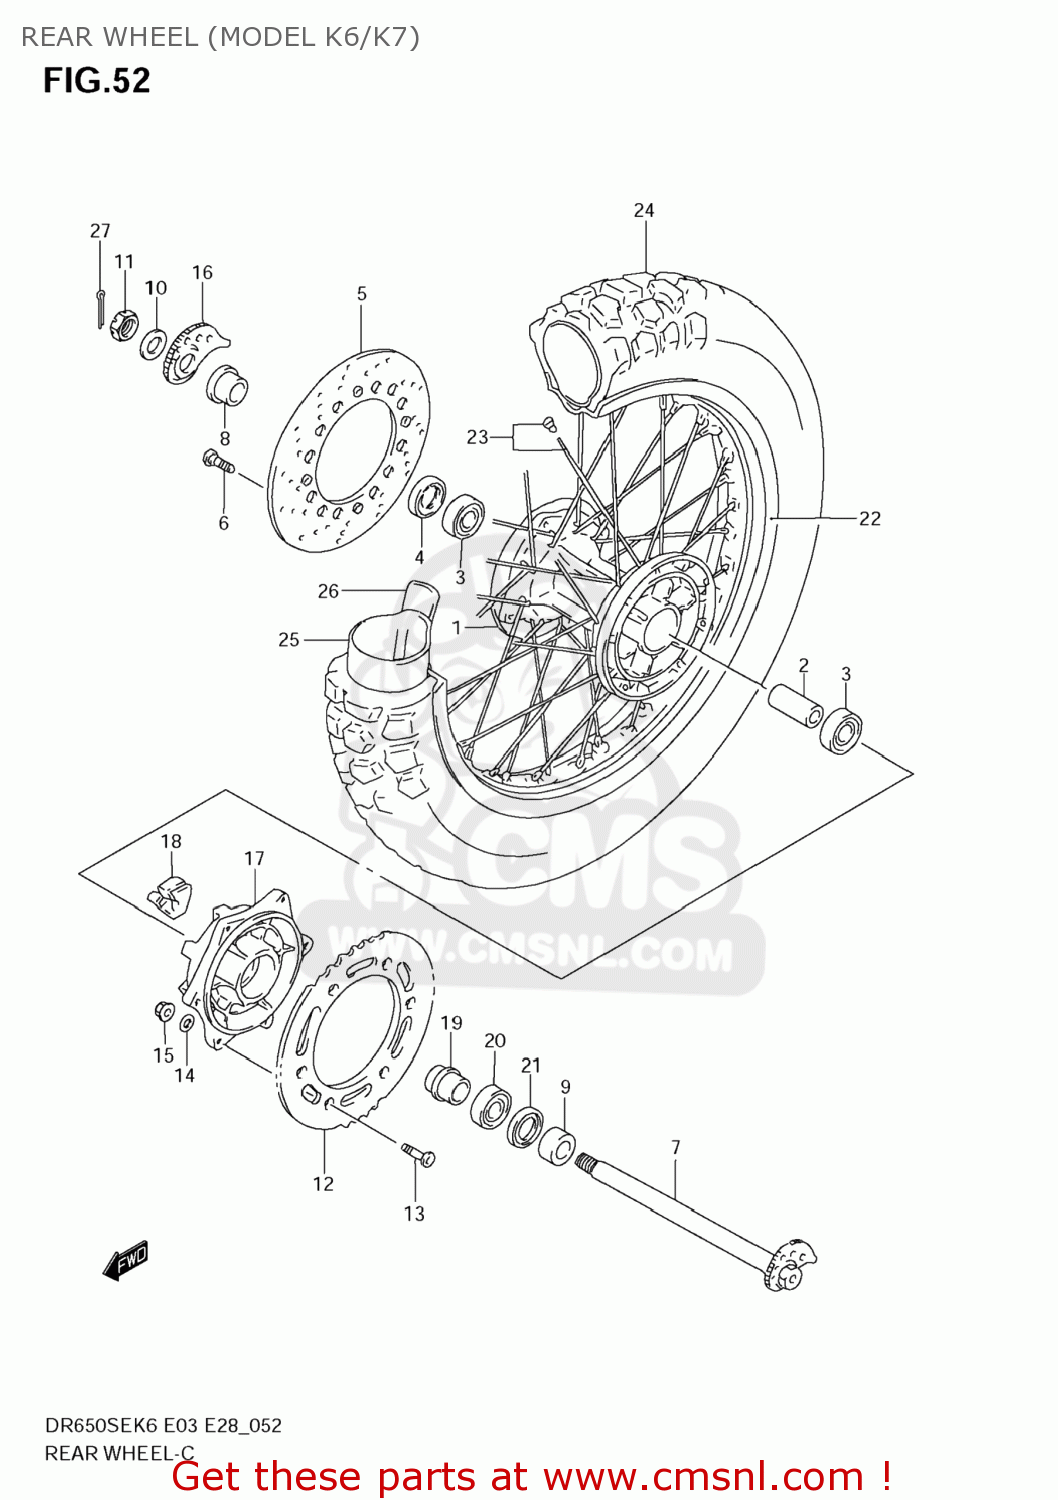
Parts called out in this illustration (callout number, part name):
1	HUB,RR WHEEL
2	SPACER,RR HUB BEARING
3	BEARING
4	SEAL,OIL(26X47X5)
5	DISC,RR BRAKE
6	BOLT(8X20)
7	AXLE,RR
8	SPACER,RR AXLE,R
9	SPACER,RR AXLE,L
10	WASHER(19X32X3.2)
11	NUT
12	SPROCKET,RR(NT:42)
13	BOLT(8X30.5)
14	WASHER
15	NUT
16	ADJUSTER,CHAIN,R
17	DRUM,RR SPROCKET MOUNTING
18	ABSORBER,RR HUB SHOCK
19	RETAINER,RR SPROCKET DRUM
20	BEARING(25X52X15)
21	SEAL,OIL(34X52X6)
22	RIM,RR WHEEL(17M/CXMT2.50)
23	SPOKE SET,RR WHEEL
24	TIRE,RR(120/90-17 64S)
25	TUBE ASSY,WHEEL INNER
26	PROTECTOR,WHEEL,INNER
27	PIN
